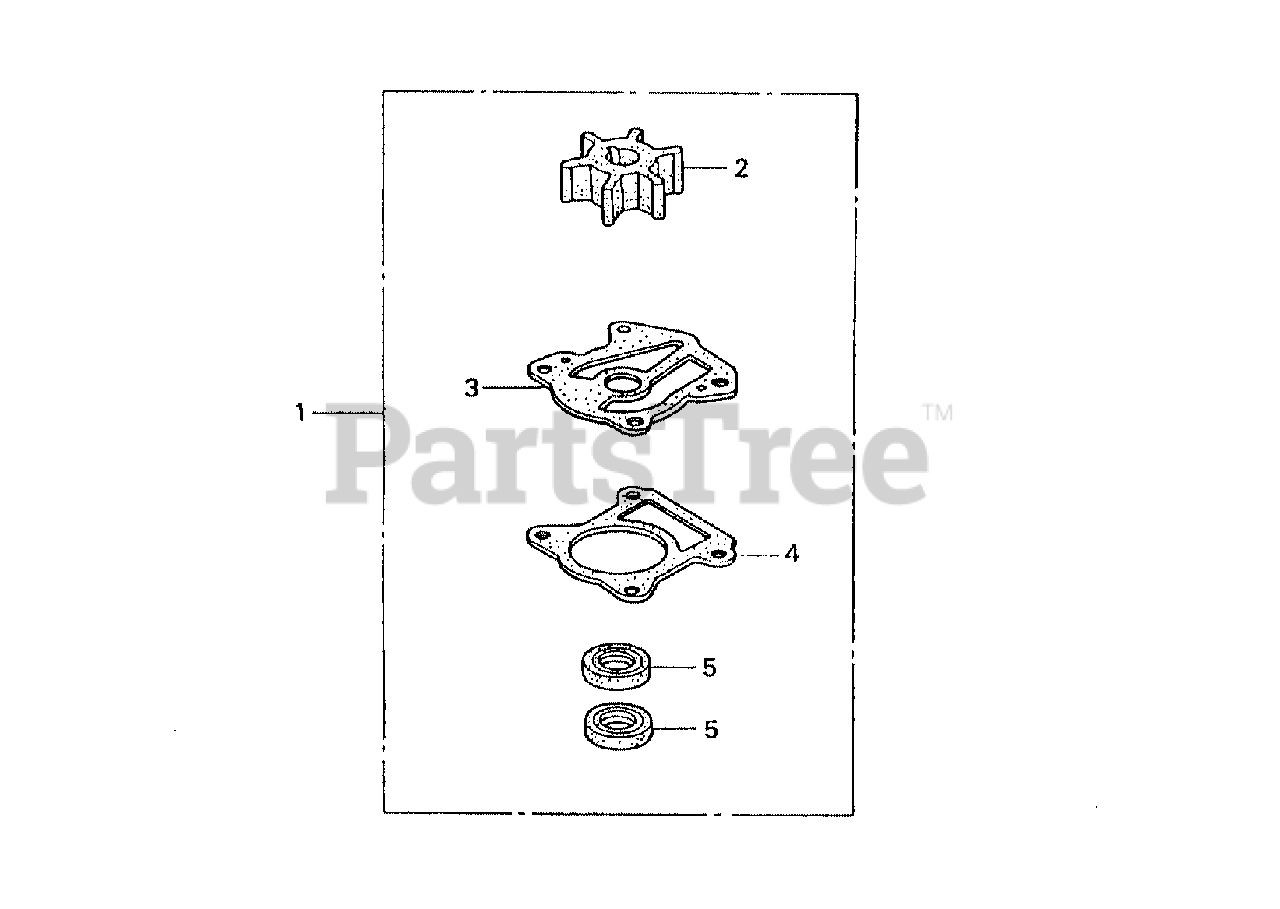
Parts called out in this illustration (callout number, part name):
1	IMPELLER KIT, WATER PUMP
2	IMPELLER, PUMP
3	GASKET B, IMPELLER
4	GASKET, WATER PUMP
5	SEAL, WATER (17X30X7)
